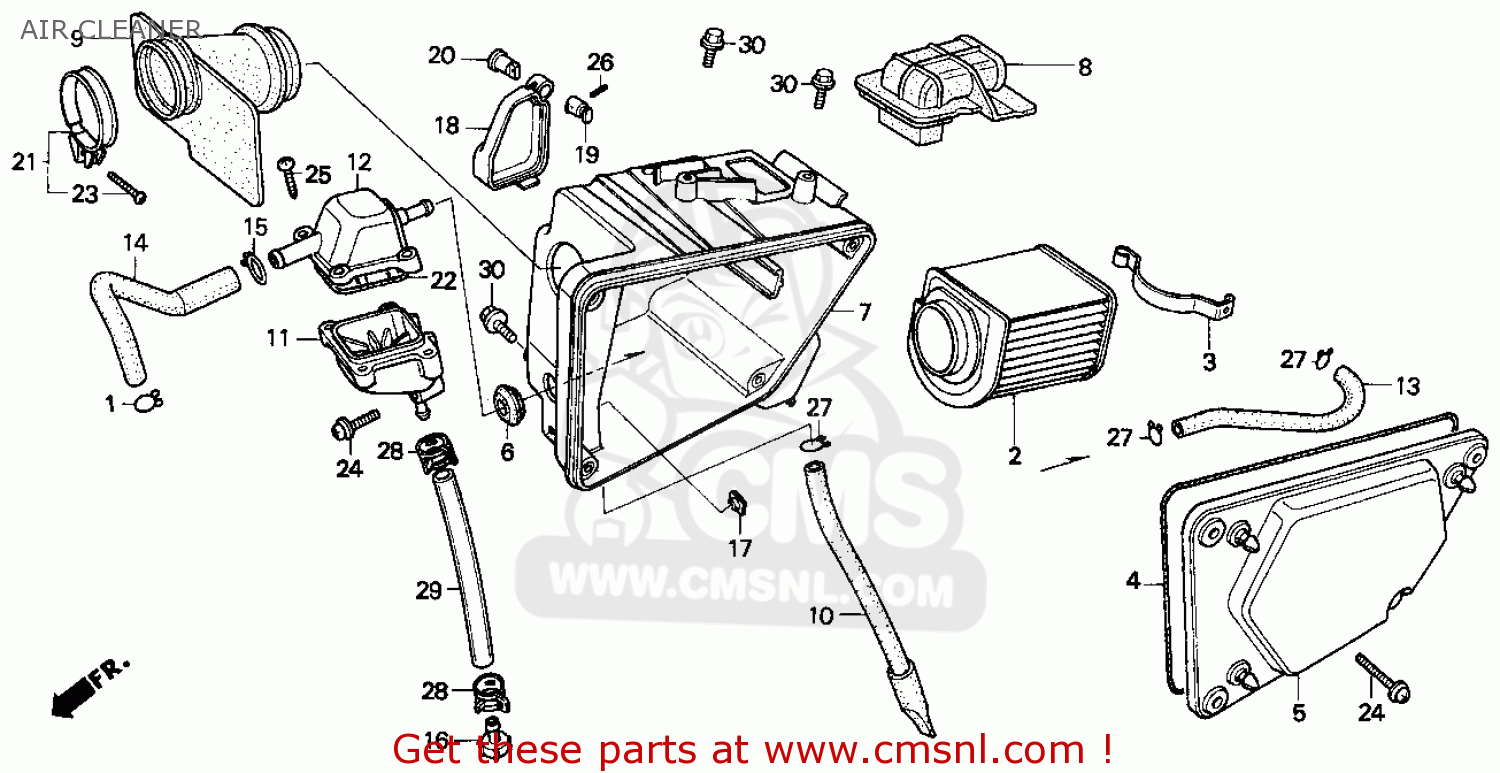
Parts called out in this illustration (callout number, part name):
1	CLIP,BRTHR TUBE
2	ELEMENT AIR/C
3	SPRING,AIR CLEANE
4	SEAL,AIR/C CVR
5	COVER,AIR CLEANER
6	GROMMET, TUBE
7	CASE COMP.,AIR CL
8	DUCT,AIR/C
9	TUBE,AIR/C.CONN.
10	TUBE COMP.,DRAIN
11	CHAMBER,BREATHER
12	COVER,BREATHER CH
13	TUBE B,BREATHER
14	TUBE,BREATHER
15	CLIP,BRTHR.TUBE
16	PLUG,BRTHR,TUBE
17	NUT,SPECIAL,6X7
18	CAP,TOOL BOX
19	BODY,KEY
20	STOPPER,KEY BODY
21	BAND,AIR CLEANER
22	SEAL,BRTHR CHBR
23	SCREW,PAN,4X25
24	SCREW-WASHER,6X28
25	SCREW,TAP,5X20
26	PIN,SPRING,2X14
27	CLIP,TUBE,B12.5
28	CLAMP,TUBE,D13
29	V.TUBE,11X15X280
